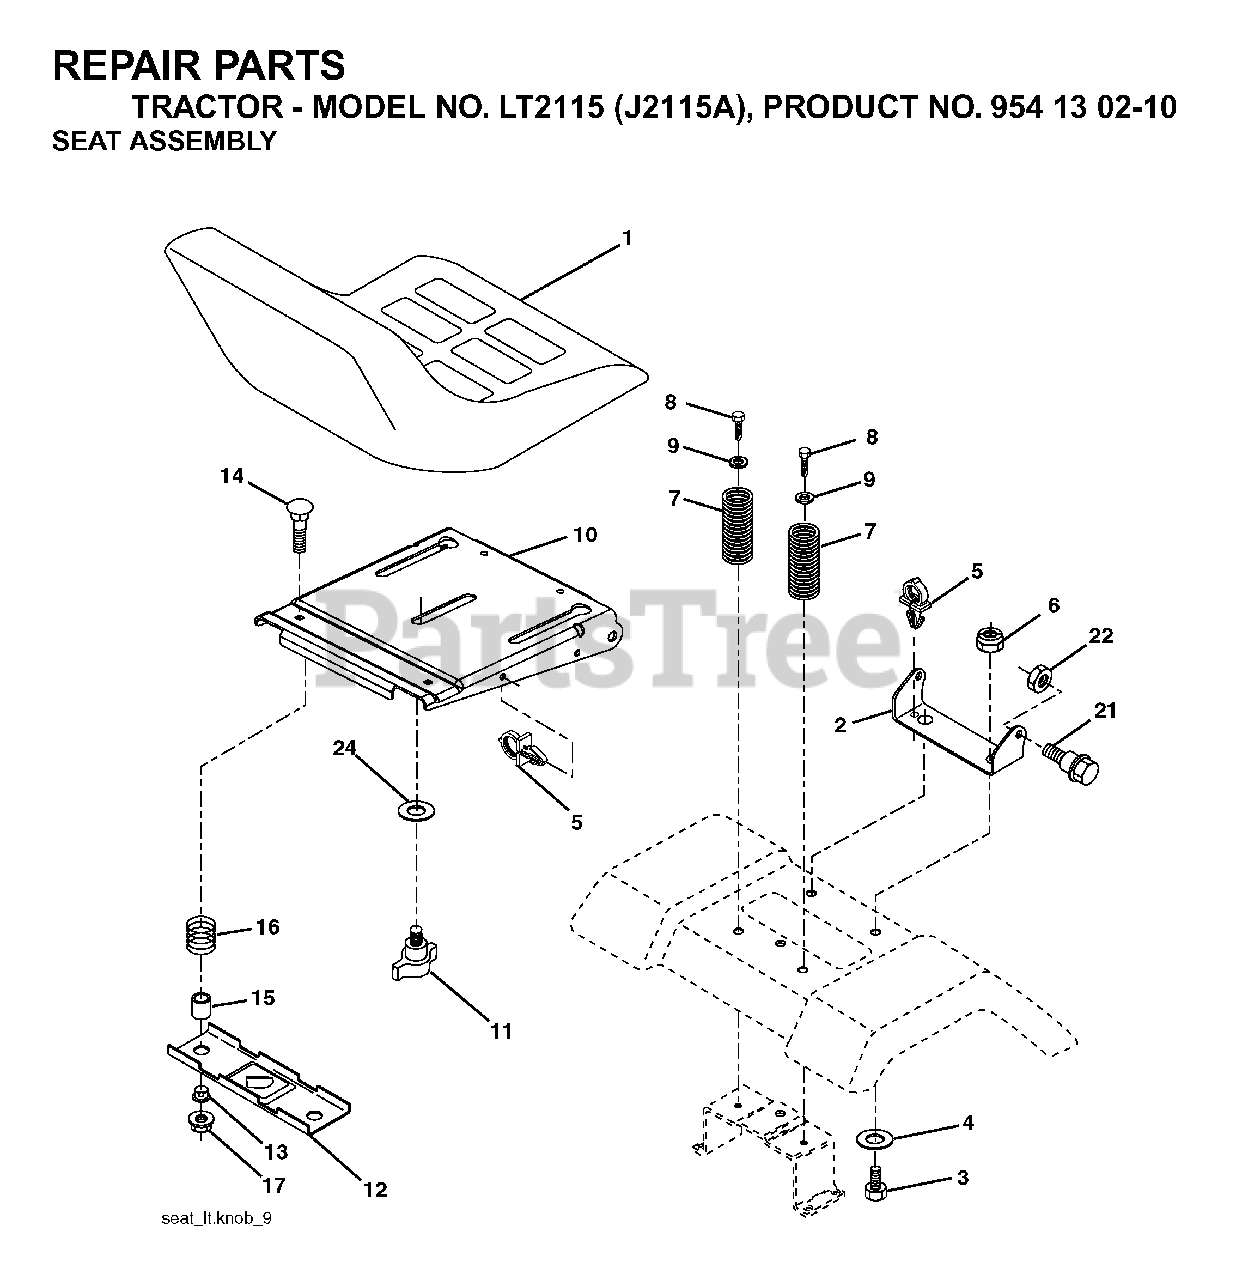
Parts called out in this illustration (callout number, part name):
1	BRKT.PIVOT.FENDER
2	SEAT PIVOT BRKT
4	WASHER PM
5	PUSH CLIP
6	NUT
7	SPRING COMPRESSION
8	SCREW 3/8-16X1
9	WASHER
11	KNOB.SEAT.ADJ.WINGNUT
12	BRKT SWITCH
14	BOLT.ROUND.HEAD.SQUARE.NECK
15	SPACER SPLIT 28X.96
17	NUT T
21	BOLT.SHOULDER.5/16-18
22	NUT.71038.31-18.HEX.NYLOCK
25	BOLT,SHOULD
